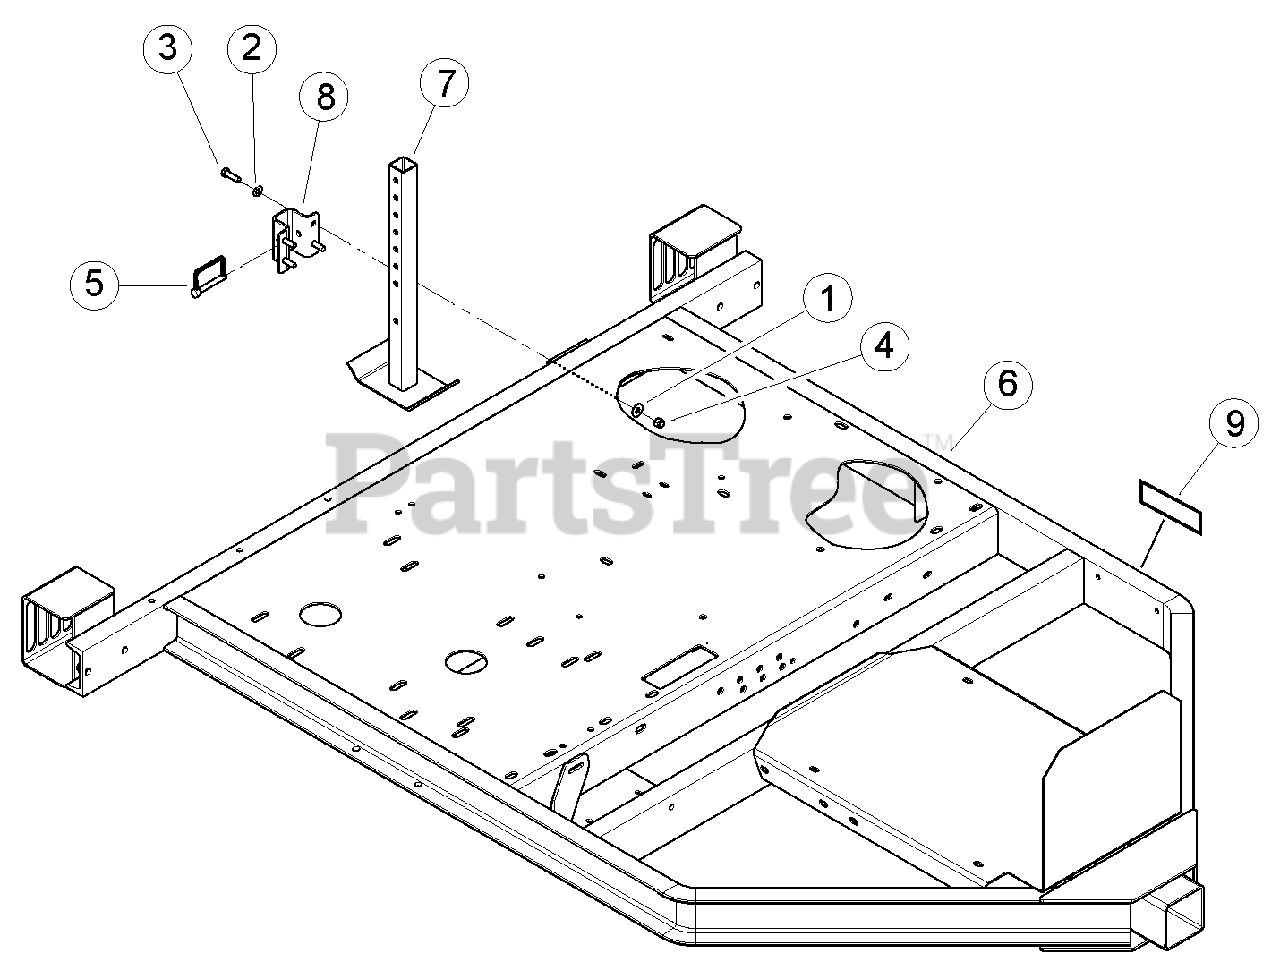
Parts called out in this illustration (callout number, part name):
1	WASHER, 3/8 FLAT ZP
2	WASHER, 3/8 SAE FLAT ZP
3	BOLT, 3/8 X 1-1/4 HEX HD GR5 ZP
4	NUT, 3/8 NC NYLOCK ZP
5	PIN, 3/8 X 2-3/4 SNAP
6	WELDMENT, CHIPPER TRAILER
7	WELDMENT, REAR STABILIZER
8	GUIDE, TRAILER SUPPORT
9	TAG, EURO VIN
